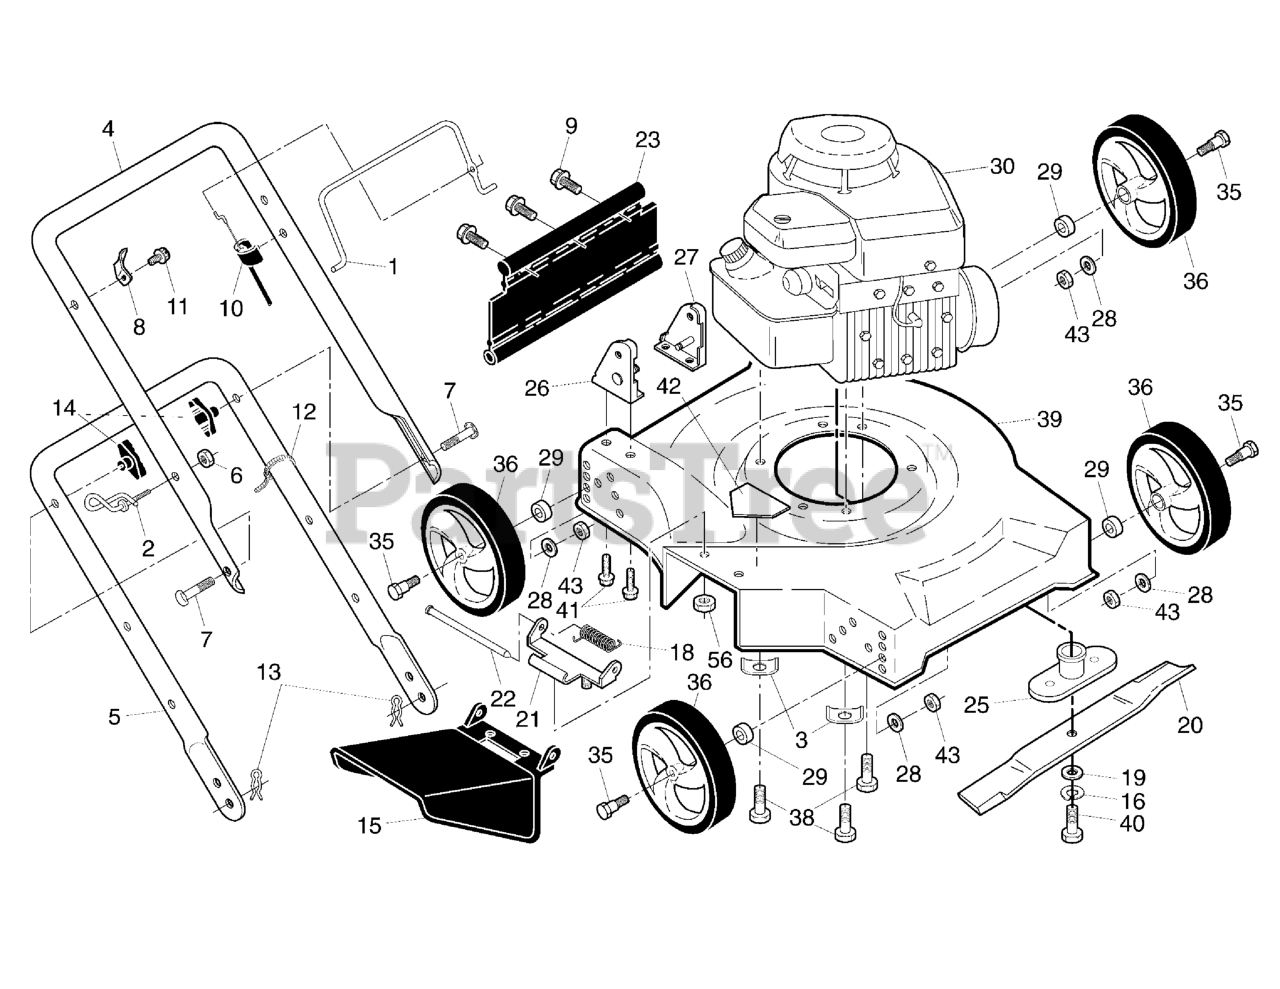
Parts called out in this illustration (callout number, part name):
1	Control Bar
2	Rope Guide
3	Engine Washer
4	Upper Handle
5	Lower Handle
6	Nut, Hex 1/4-20
7	Bolt, Carriage
8	Up-Stop Bracket
9	Screw, Hex Washer Head, Self-Tapping, #10-24 X 1/2
10	Cable, Engine Zone Control
11	Screw, Threaded, Rolled #10-16 x 5/8
12	Wire Tie
13	Hairpin, Cotter
14	Knob, Handle
15	Discharge Guard
16	Helical Lock Washer
18	Spring, Hinge
19	Washer, Hardened
20	Blade, 20"
21	Bracket, Hinge
22	Rod, Hinge
23	Rear Skirt
25	Blade Adapter
26	Handle Bracket Assembly, RH
27	Handle Bracket Assembly, LH
28	Washer
29	Spacer
30	* Engine, Briggs & Stratton
35	Bolt, Shoulder 3/8-16 x 2-1/2
36	Wheel & Tire Assembly
38	Screw, Hex Head, Threaded, Rolled 3/8-16 x 1
39	Housing Kit
40	Screw, Hex Head, Machine, Grade 8, 3/8-24 x 1-3/8
42	Danger Decal
43	Nut, Hex, Nylock 3/8-16
56	Locknut, Hex 1/4-20
